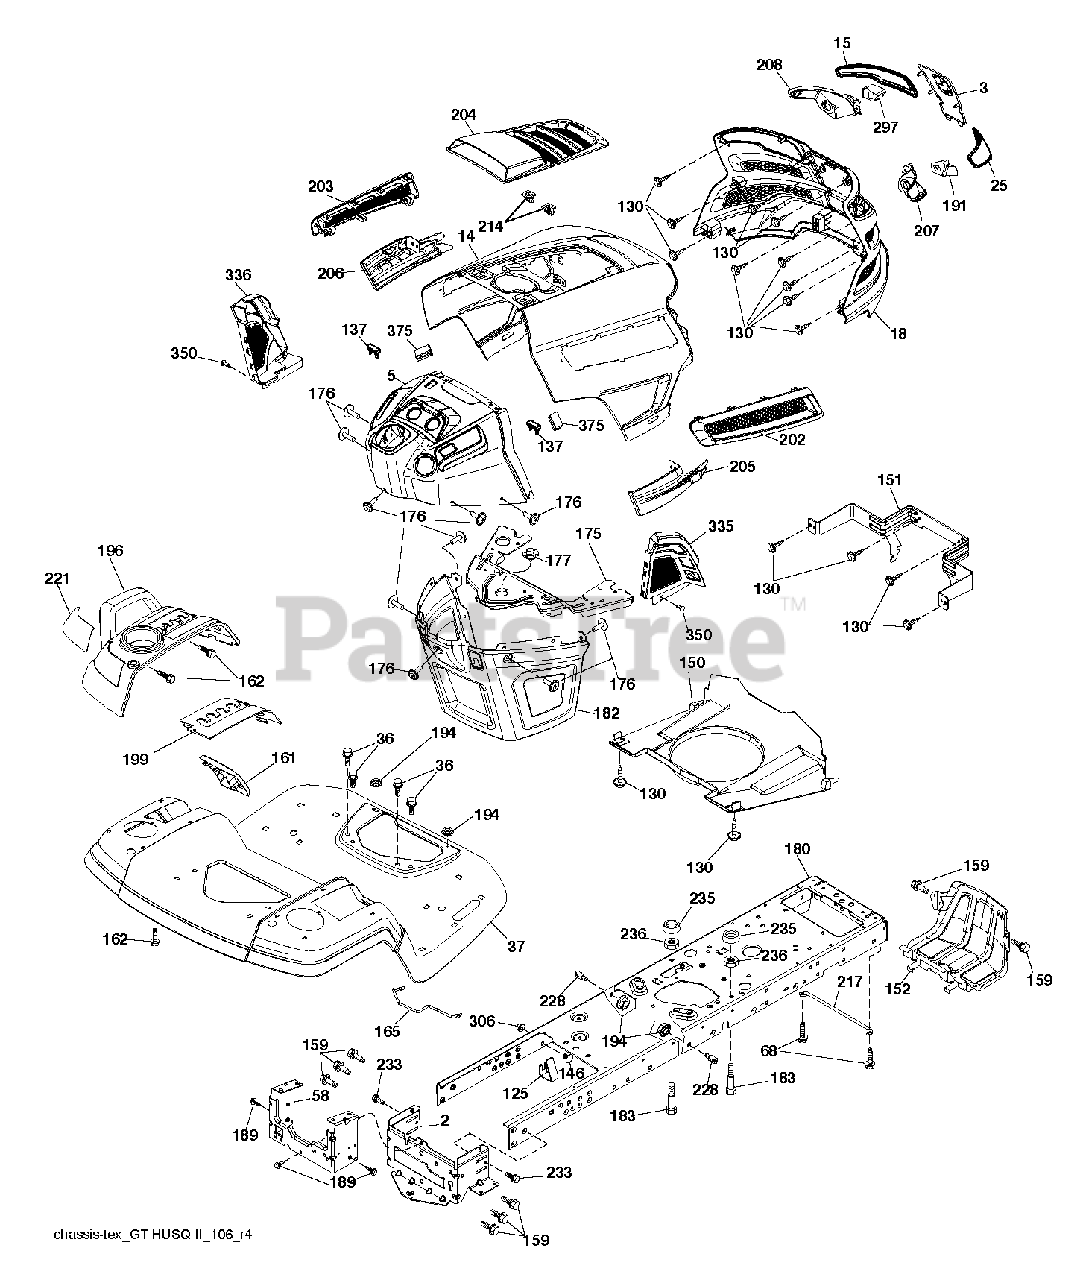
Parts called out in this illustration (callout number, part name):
2	DRAWBAR.LOWER.2PC.18/22
3	APPLIQUE.SUBASM.GT.HUSQ.II
5	DASH.UPP.GT2.DUAL.RD.
14	HOOD.ASM.HUSQVARNA.GT.TEX.ORAN
15	LENS.HEADLIGHT.LH.GTII.2011
18	GRILLE.SUBSTRATE.2011.
25	LENS.HEADLIGHT.RH.GTII.2011
36	SCREW 5/16"
37	FENDER.PNT.TX.GT.CH/FW/DL.HUSQ
58	DRAWBAR.UPPER.2PC,LRG.FENDER
68	SCREW LT
125	CLIP.FUEL.LINE
130	SCREW.#10 X 0.750.BOS
137	BUMPER DASH
146	BOLT.RDHD.SHT.SQNK.3/8-16X5/8
150	AIR.DUCT.GTV.BLACK
151	BRACKET.PIVOT.HOOD.GT.HUSQ.II
152	SHIELD.BROWNING.PNT.GT.V2
159	SCREW, 3/8-16X3/4
161	CONSOLE.WINDOW.FUEL.HUSQ.GT
162	SCREW.HI-LO.CONSOLE
165	SUPPORT.TANK.REAR.B/TE
175	PLATE.CROSSMEMBER.HUSQ
176	SCREW.#10-24X5/8.RN.QU
177	BUSHING STEERING
180	CHASSIS.TEX.BOLTED
182	DASH.LOWER.COMMON.12V.ADAPTOR
183	BOLT.5/16-18X1-1/4 FULL THD
189	SCREW
191	INSERT.REFLECTIVE.RH.HUSQ.GTII
194	NUT LOCK HEX FLANGE 5/16-18
196	CONSOLE.ASM.DECKLIFT.HUSQGT.DL
199	PLATE.DECK.LIFT.HUSQVARNA.GT
202	VENT.SIDE.RH.GT.HUSQ.II.
203	VENT.SIDE.LH.GT.HUSQ.II.498
204	VENT.TOP.HUSQ.GT2
205	SIDE.TRIM.RH.GT.HUSQ.II
206	SIDE.TRIM.LH.GT.HUSQ.II.GRAY
207	BEZEL LIGHT.RH.GT.II.MYLAR
208	BEZEL LIGHT.LH.GT.II.MYLAR
214	CLIP.RETAINER.TINNER.
217	ROD.PIVOT.HOOD
221	REFLECTOR.LH.TEX GT HU
228	STUD.FASTNER.W/ANTI-ROTATE
233	BOLT.SHOULDER
235	SPACER FENDER
236	NUT.CENTERLOCK.5/16-
297	INSERT.REFLECTIVE.LH.HUSQ.GTII
306	NUT LOCK FLG 3/8-16 UNC
335	COVER.LOWER.DASH.RH.BLACK
336	COVER-LH.LOWER.DASH.GT2.BLACK
350	CLIP.X-MAS.TREE
375	BUMPER CLIP-ON. DASH 1"
